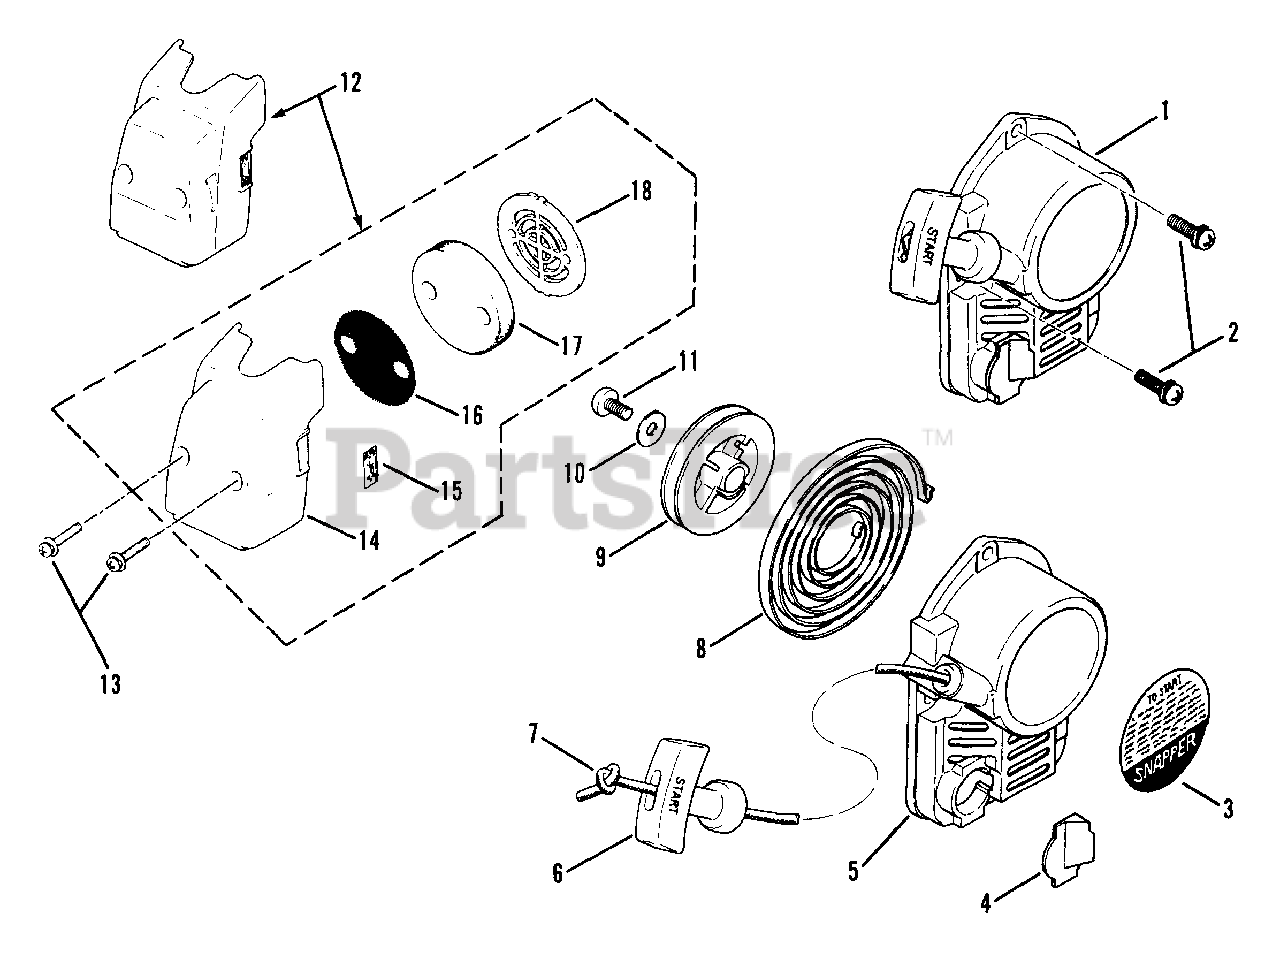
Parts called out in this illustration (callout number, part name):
1	RECOIL STARTER ASSM'Y.
2	SCREW/WASHER
3	DECAL, Starting
5	HOUSING, Starter
6	KNOB, Starter
7	ROPE, Starter
8	SPRING, Spiral
12	AIR CLEANER ASSM'Y.
13	SCREW/WASHER, M4 x 25mm
14	COVER, Air Cleaner
15	NAMEPLATE, Choke
17	ELEMENT
18	HOLDER, Element
